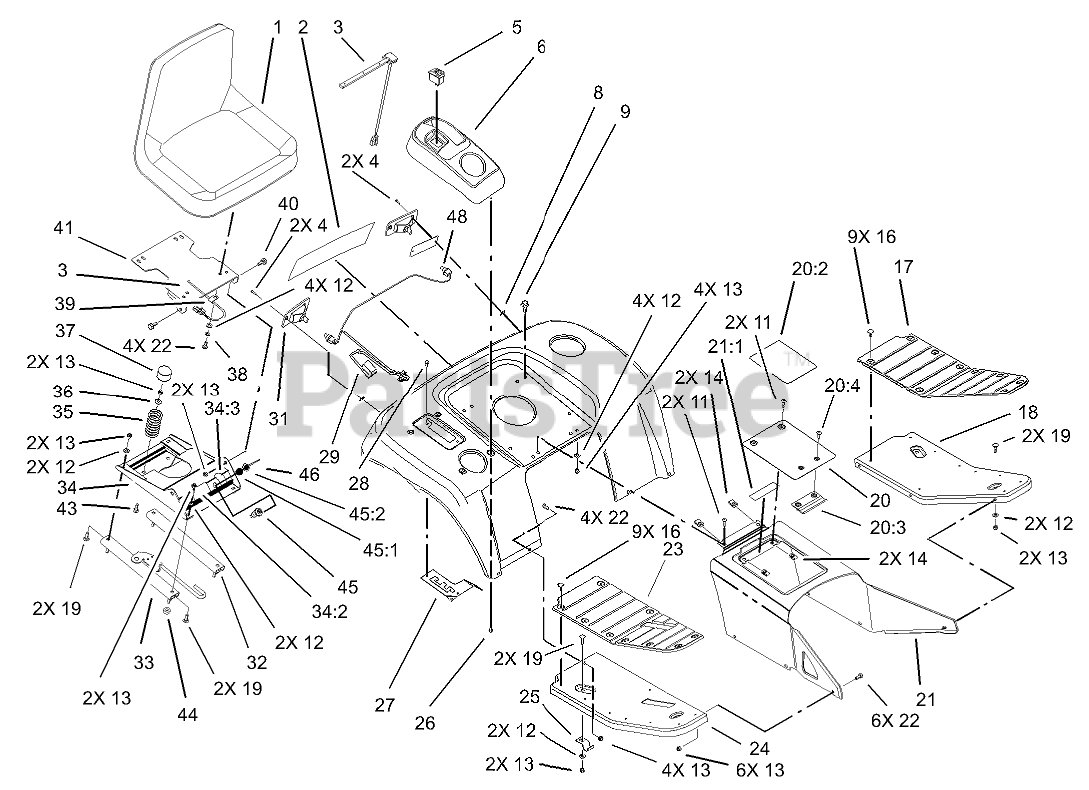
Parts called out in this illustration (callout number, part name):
1	SEAT
2	Decal-Rear Fender
3	SWITCH-SEAT
4	SCREW-PPH
5	SWITCH-CRUISE
6	POD-CONTROL
8	NUT-SPEED
9	SCREW-HHF
11	SCREW-HH
12	WASHER-PLAIN
13	NUT-LOCK, NI
16	FASTENER-PANEL
17	PAD-FOOTREST, LH
18	FOOTREST-LH
19	SCREW-CARR
20	COVER / DECAL ASM
20:2	DECAL-DANGER
20:3	RETAINER-COVER
20:4	SCREW-PPH
21	TUNNEL ASM
21:1	DECAL-DANGER
22	SCREW-HH
23	PAD-FOOTREST, RH
24	FOOTREST-RH
25	BRACKET-FOOTREST
26	SCREW-HHFTF
27	GATE-HI / LO SHIFT
28	SCREW-HWH
29	HARNESS-REAR
31	LAMP-TAILLIGHT
32	SLIDE-SLAVE, SEAT
33	SLIDE-LATCH, SEAT
34	SEAT BASE ASM
34:2	DECAL-DANGER
34:3	DECAL
35	SPRING-COMPRESSION
36	BUSHING
37	CAP-SPRING, SEAT
38	WASHER-LOCK
39	CLAMP-R
40	BOLT-SHOULDER
41	MOUNT-SEAT
43	SCREW-CARR
44	WASHER-FLAT
45	STARTER SWITCH ASM
45:1	WASHER-TOOTH, INTERNAL
45:2	NUT-HH
46	KEY-IGNITION
48	LIGHT BULB
